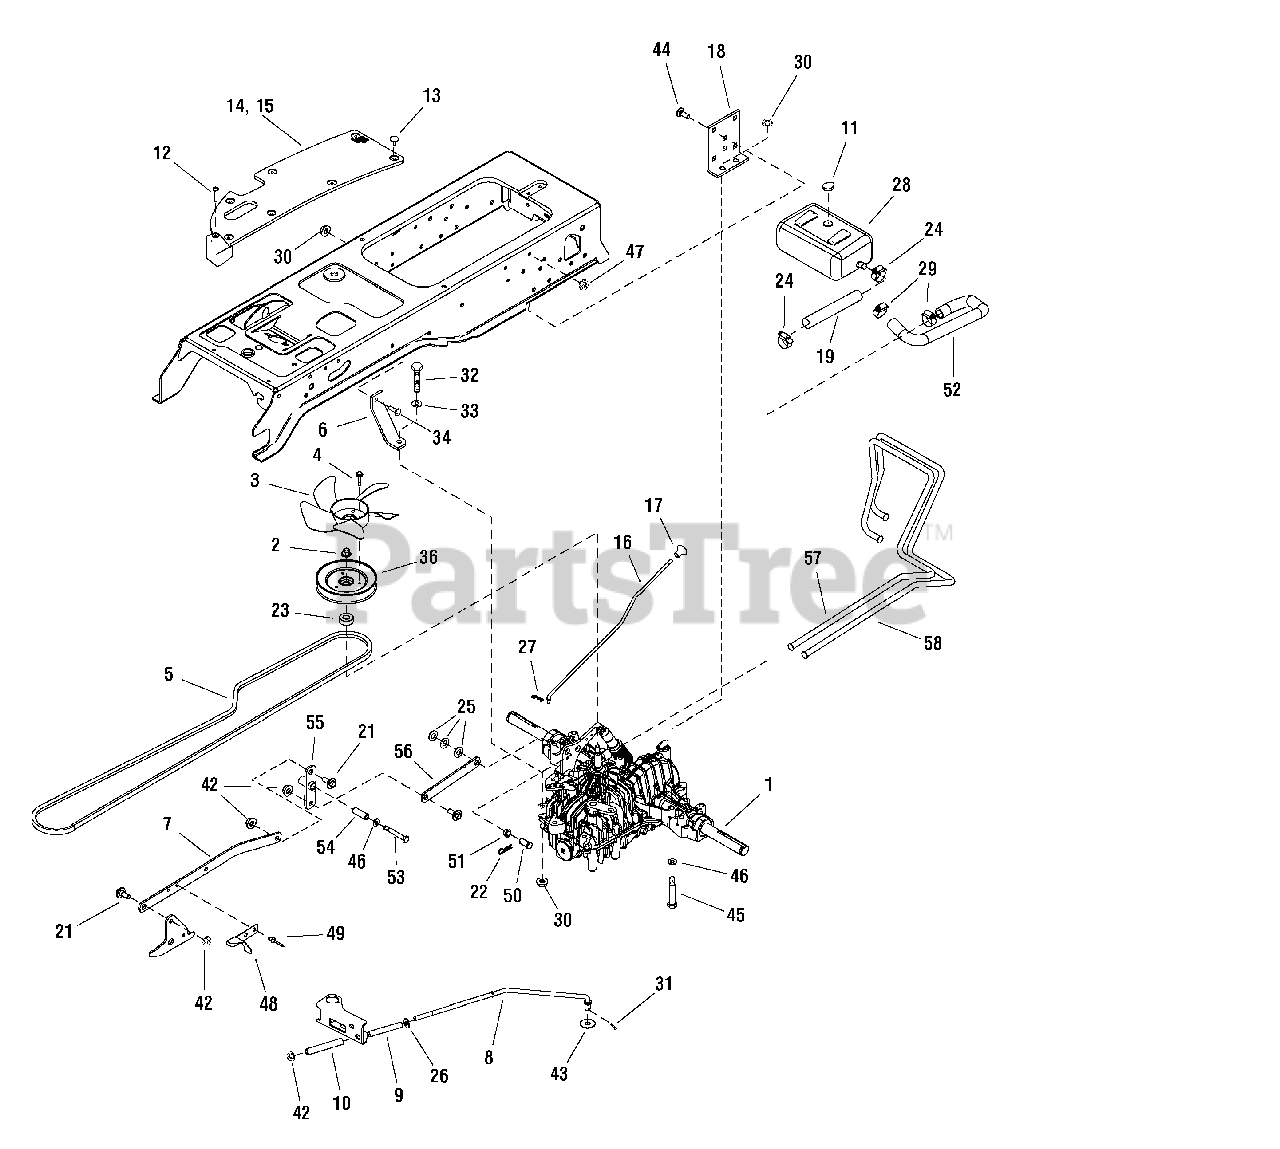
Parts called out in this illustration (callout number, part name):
1	TRANSMISSION, 4WD Tuff Torq K664
2	PULLEY
3	FAN
4	SCREW, Hex Taptite 1/4-20 x 1-1/2
5	V-Belt, 94.05" EL
6	STRAP, Torque
7	CONTROL ARM, Front
8	ROD, Brake
9	SPRING, Compression
10	SPRING, Compression
11	CAP, Tank
12	SCREW, Pan Hd Torx,Taptite, 1/4-20 x 1-1/4
13	FASTENER
14	PAD, Footrest LH
15	PAD, Footrest RH
16	ROD, Free Wheel
17	KNOB, Internal Thread
18	BRACKET, Transmission
19	HOSE, Return
21	BOLT, SHLDR, 3/8-16 x 0.94
22	CLIP, Hair Pin
23	SPACER, 0.607 ID x 1.25 OD x 0.47
24	CLAMP, Hose
25	WASHER, Flat, 1/2
26	WASHER, Flat, 3/8
27	RETAINER, Pin
28	EXPANSION TANK
29	CLAMP, Hose Worm #12
30	NUT, Hex ESNA Flange 5/16-18
31	PIN, Cotter, .094 x 3/4
32	CAPSCREW, Hex Hd, 5/16-18 x 2-1/2
33	WASHER, Flat 5/16 x 7/8 x 1/8
34	BOLT, Carriage, Short Neck, 5/16-18 x 1
36	NUT, Hex Flange, M10-1.50
42	NUT, Hex ESNA Flange, 3/8-16
43	WASHER
44	BOLT, Carriage 3/8- 16 x 1
45	CAPSCREW, Hex Hd 5/16-18 x 3
46	WASHER, Flat 5/16
47	NUT, Hex Keps 3/8-16
48	ACTUATOR, Switch
49	RIVET, Pop 1/4 x 1/2
50	PIN, Clevis 1/2
51	BUSHING, Nyliner
52	HOSE, Hydraulic
53	CAPSCREW, Hex Hd 5/16-18 x 2-1/4
54	SPACER, 1-1/2
55	PIVOT, Control Assy 4WD
56	ARM, Control Rear
57	TUBE, Front Trans. To Bottom Axle
58	TUBE, Rear Trans. To Top Axle
